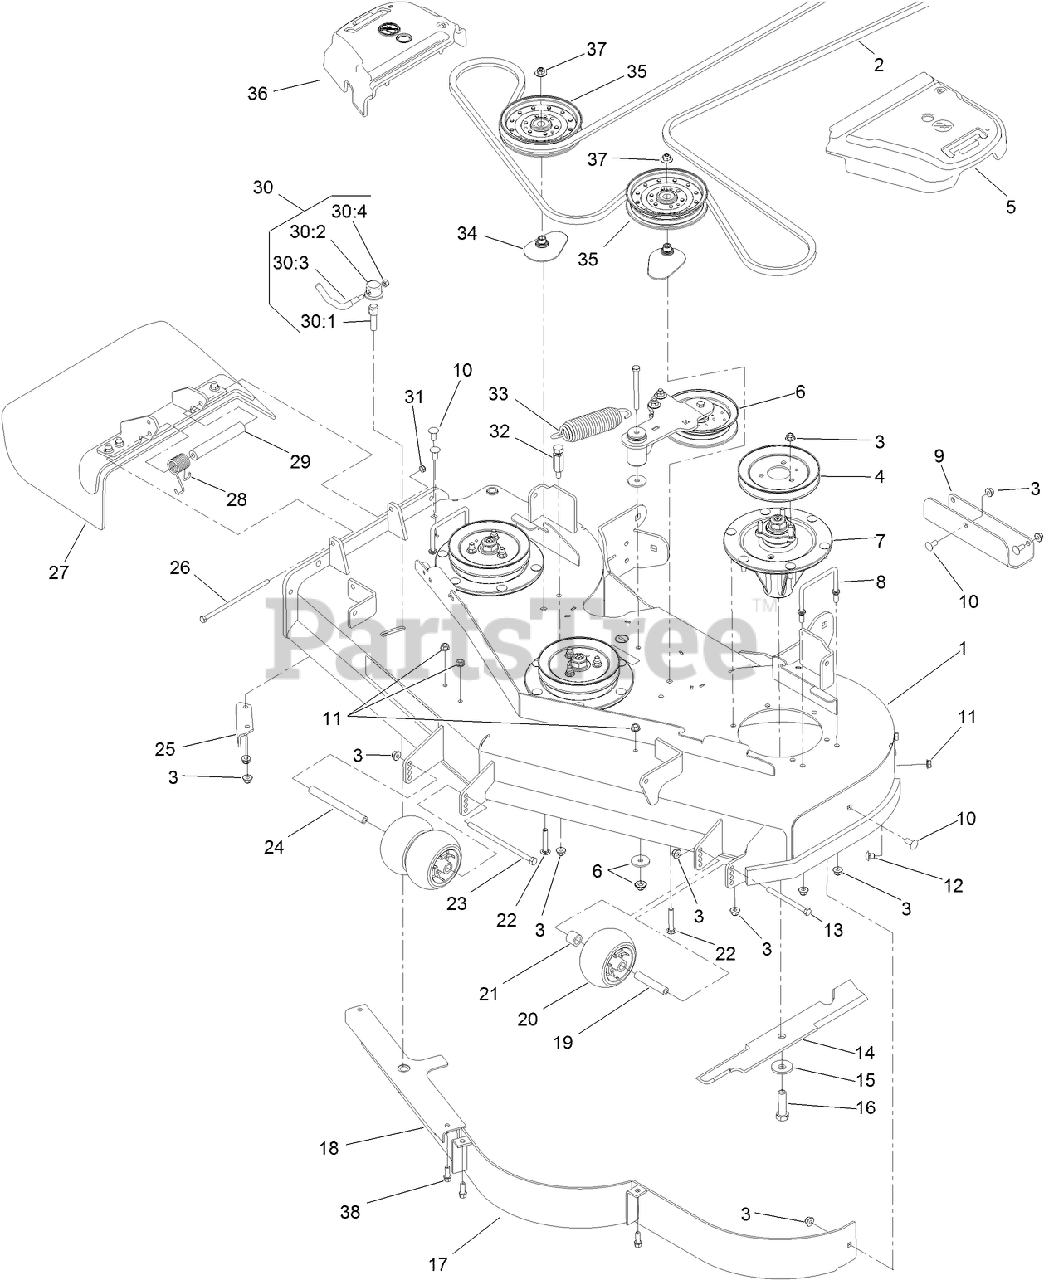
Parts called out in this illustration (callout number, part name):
1	DECK DECAL ASM
2	BELT-V
3	NUT-HF, NI
4	PULLEY
5	COVER-BELT, LH
6	IDLER ARM ASM
7	SPINDLE ASM
8	WIREFORM-COVER
9	PLATE-SKID
10	SCREW-CARR
11	NUT-HHF, WHIZ
12	SCREW-CARR
13	SCREW-HH
14	BLADE-18IN, HI FLOW
15	Washer-Blade Bolt, Heavy
16	SCREW-BLADE
17	BAFFLE ASM
18	BAFFLE
19	TUBE-SPANNER
20	ROLLER-SCALP, ANTI
21	TUBE-SPACER
22	BOLT-CARR, SHORT NECK
23	SCREW-HH
24	SPACER-WHEEL
25	BAFFLE-DISCHARGE
26	SCREW-HH
27	RUBBER DEFLECTOR ASM
28	SPRING-TORSION
29	SPACER
30	LEVER ASM
30:1	Screw-Lock
30:2	CAP-LOCK
30:3	Lever-Lock
30:4	NUT-LOCK, NI
31	NUT-LOCK, NI
32	ANCHOR-SPRING, TALL
33	SPRING-EXTENSION
34	SPACER-PULLEY
35	PULLEY-IDLER, FLAT
36	COVER-BELT, RH
37	NUT-FLANGE, NI
38	SCREW-HWH
